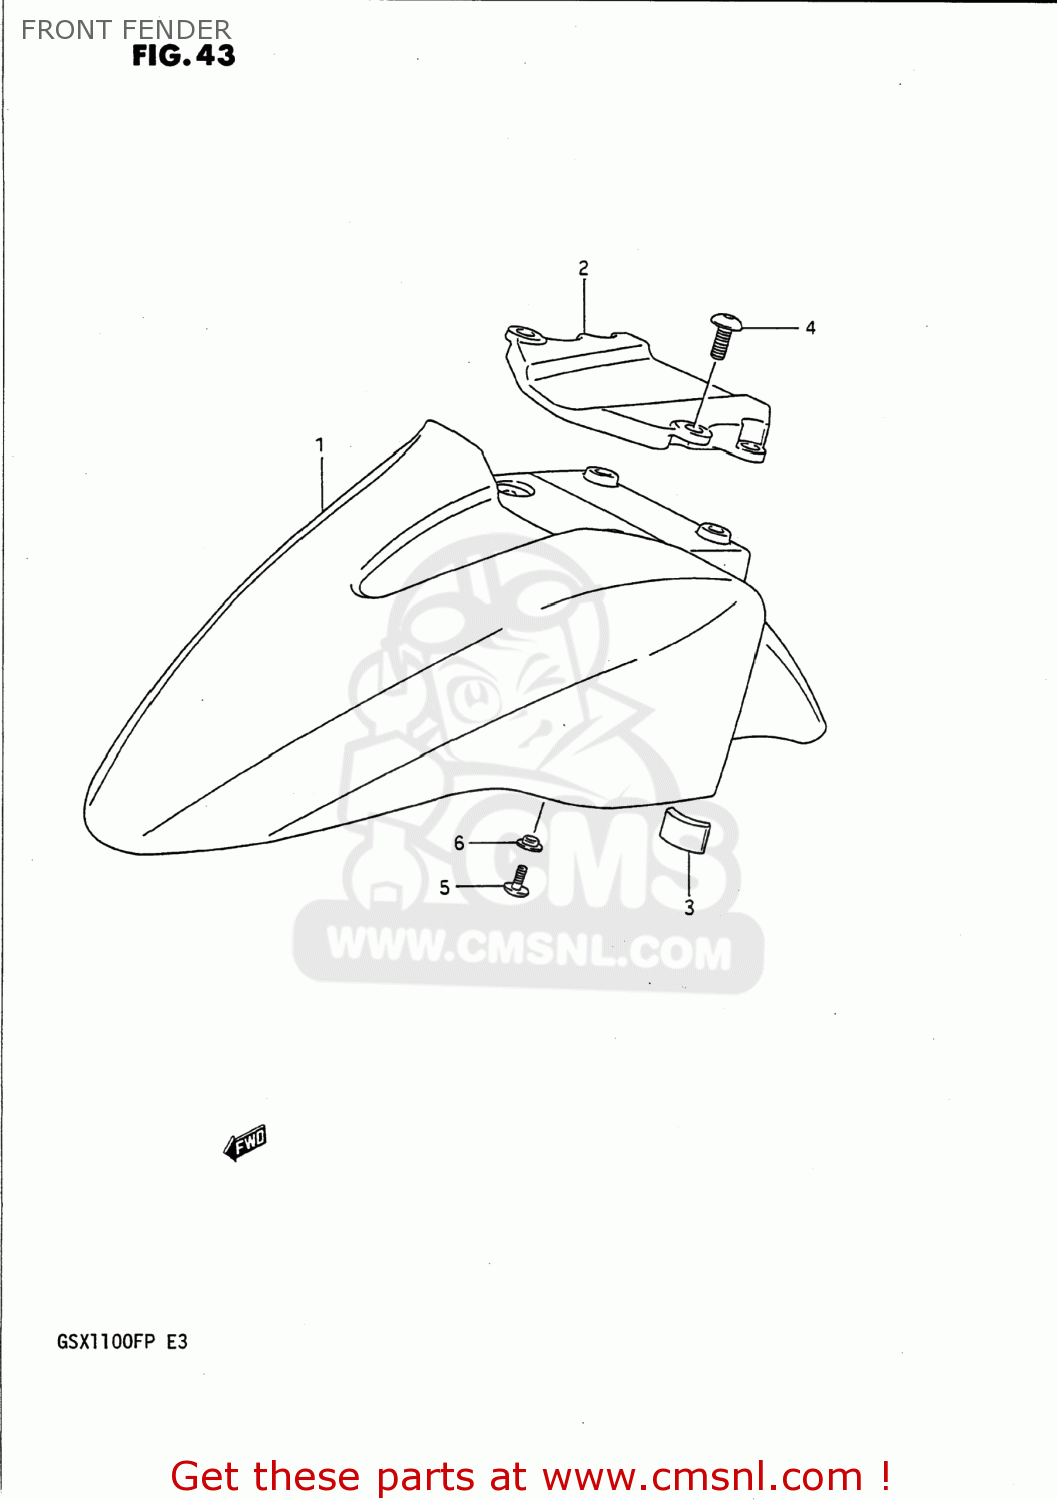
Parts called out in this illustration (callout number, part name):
1	FENDER,FRONT
2	BRACE,FR FENDER
3	CUSHION,FR FENDER
4	SCREW(8X16)
5	SCREW, FRONT & REAR
6	WASHER
